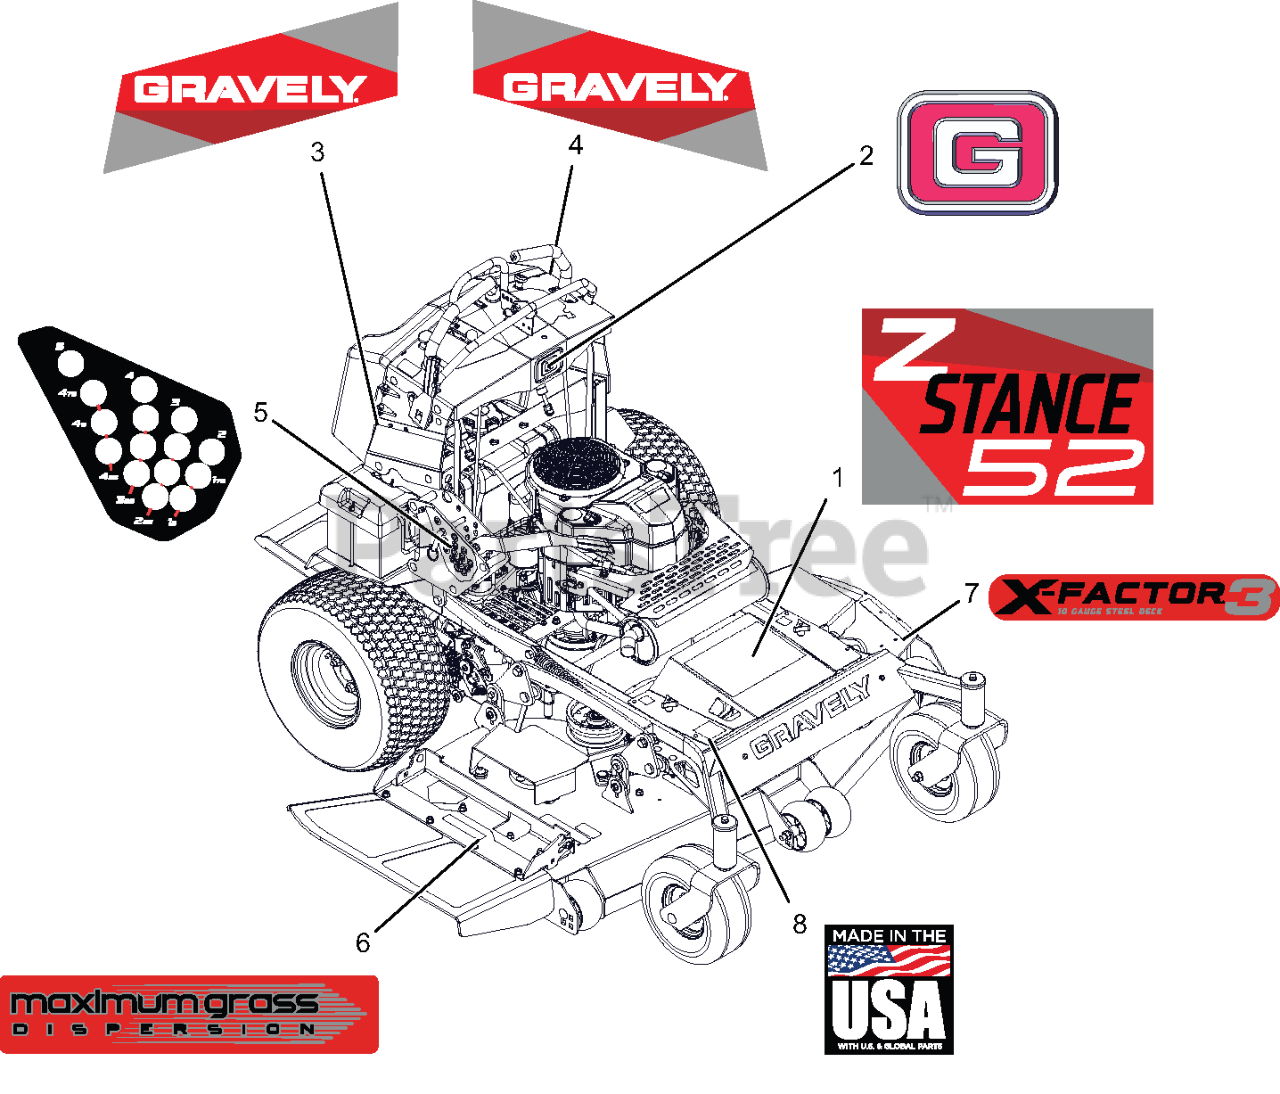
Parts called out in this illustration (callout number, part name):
1	DECAL- Z-STANCE 52"
2	DECAL, GRAVELY BRAND
3	DECAL,RH GRAVELY LOGO
4	DECAL- LH GRAVLEY LOGO
5	DECAL- DECK - HEIGHT ADJUST
6	DECAL, DECK - MAX GRASS
7	DECAL, X-FACTOR 3
8	DECAL, MADE IN USA
